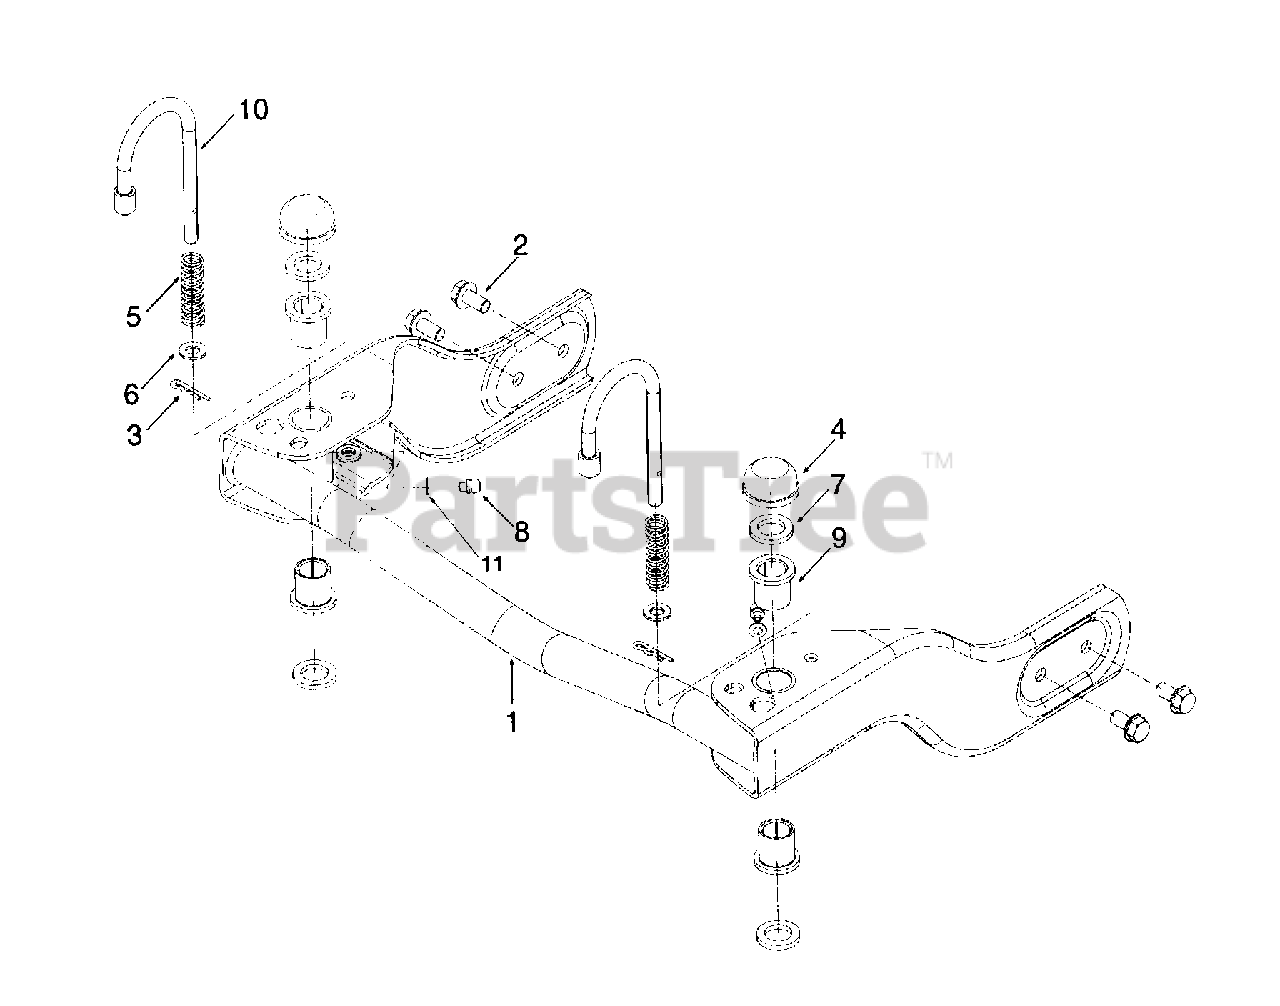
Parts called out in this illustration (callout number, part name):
1	Bracket Assembly, Front Wheel
2	Screw, Hex Wash. Hd. Tapp, 5/16-18 x .62
3	Pin, Internal Cotter
4	Cap, Push, 5/8
5	Spring, Compression
6	Washer, Flat, .330 x .630 x .06
7	Washer, Flat, .64 x 1.12 x .12
8	Fitting, Lube, 3/16
9	Bearing, Flange, .632 ID
10	Pin, Front Wheel Lock
11	Washer, Flat, .203 ID x .403 OD .04
